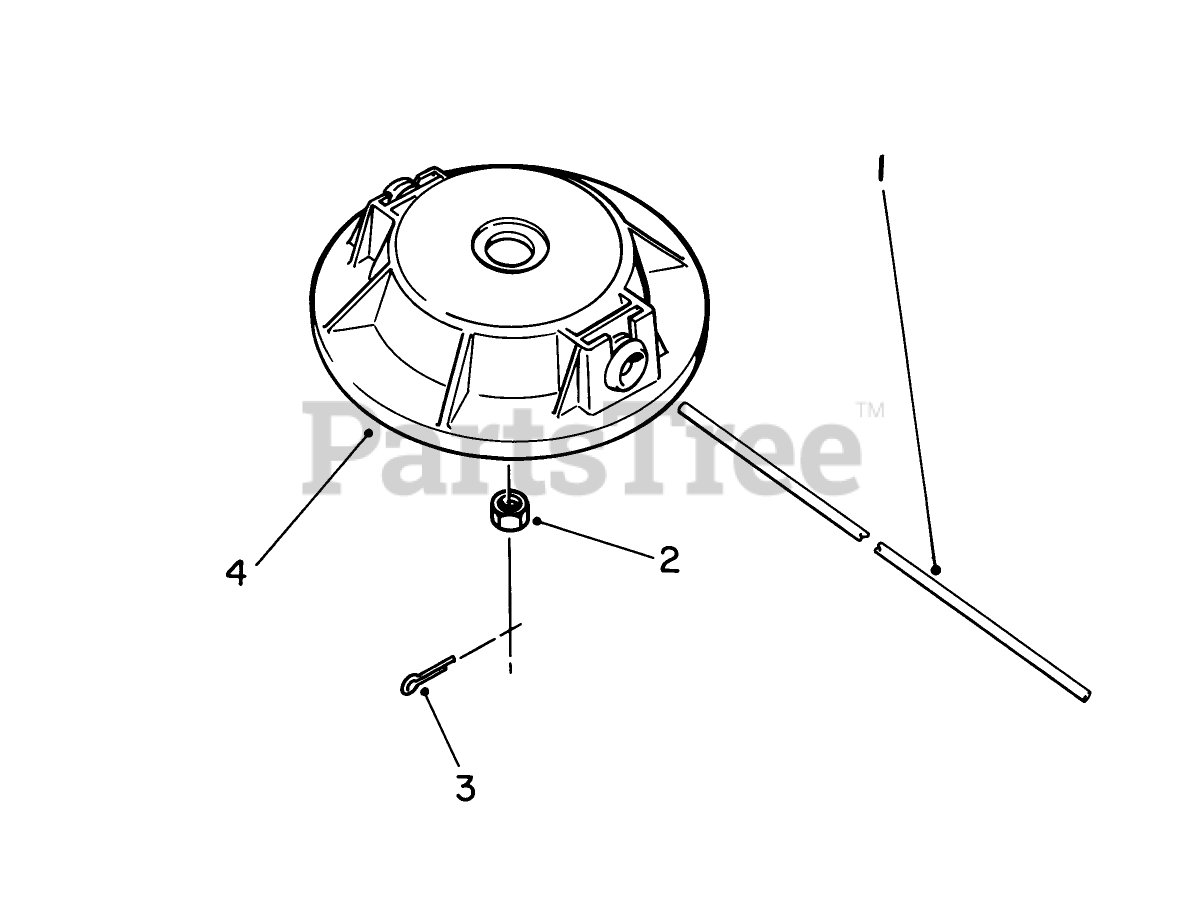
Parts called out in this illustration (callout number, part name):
1	Line-Cutting
3	1/16 X 1 LG COTTER PIN
4	CUTTER HEAD-PLASTIC
